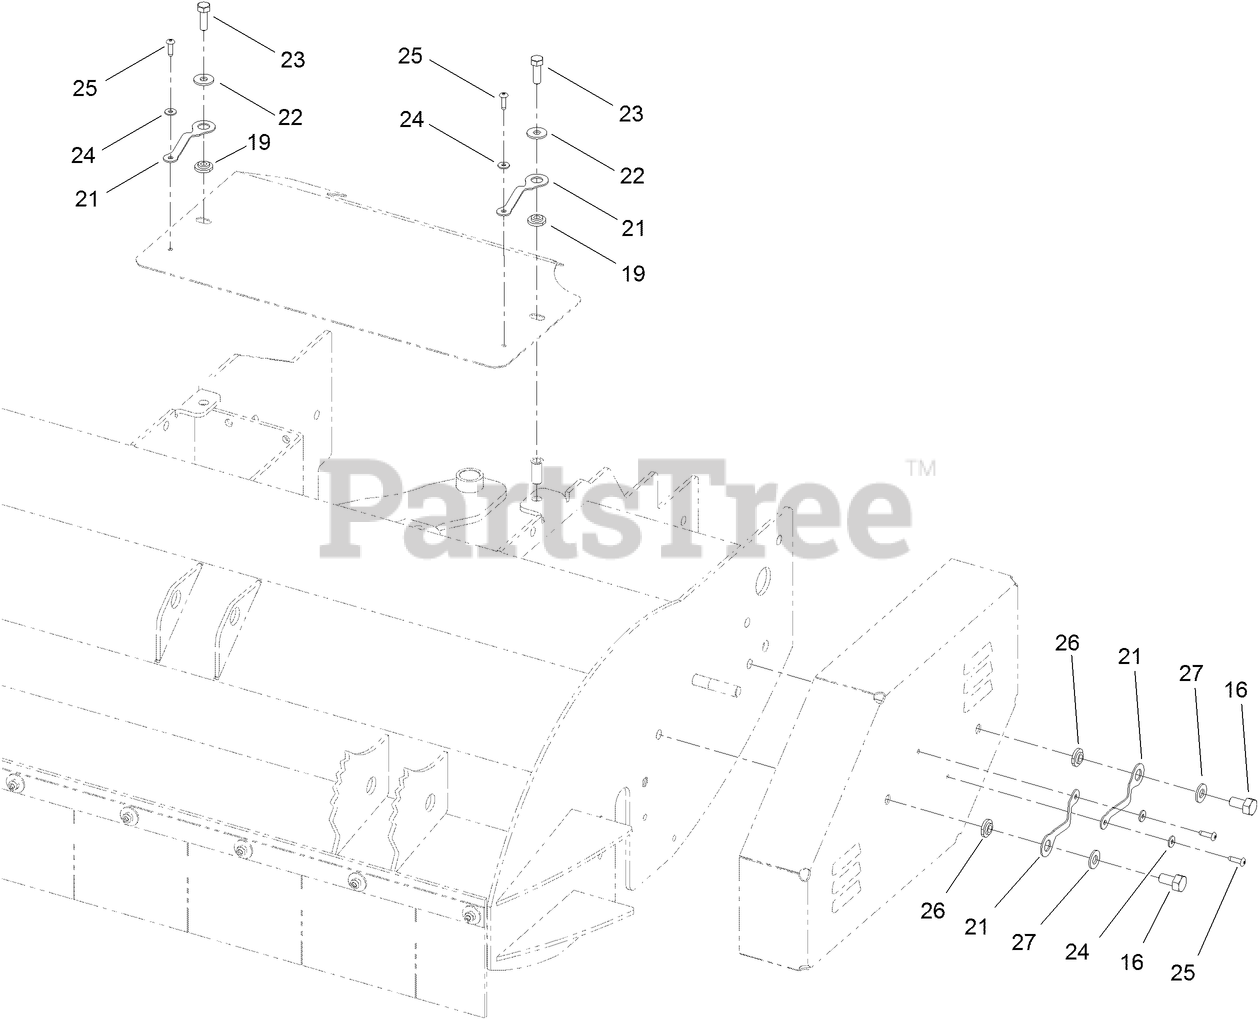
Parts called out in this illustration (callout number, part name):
16	SCREW-HH
19	NUT-RETAINER
21	LANYARD-3 INCH
22	WASHER
23	SCREW-HH
24	WASHER
25	RIVET
26	NUT-RETAINER
27	WASHER-PLAIN
